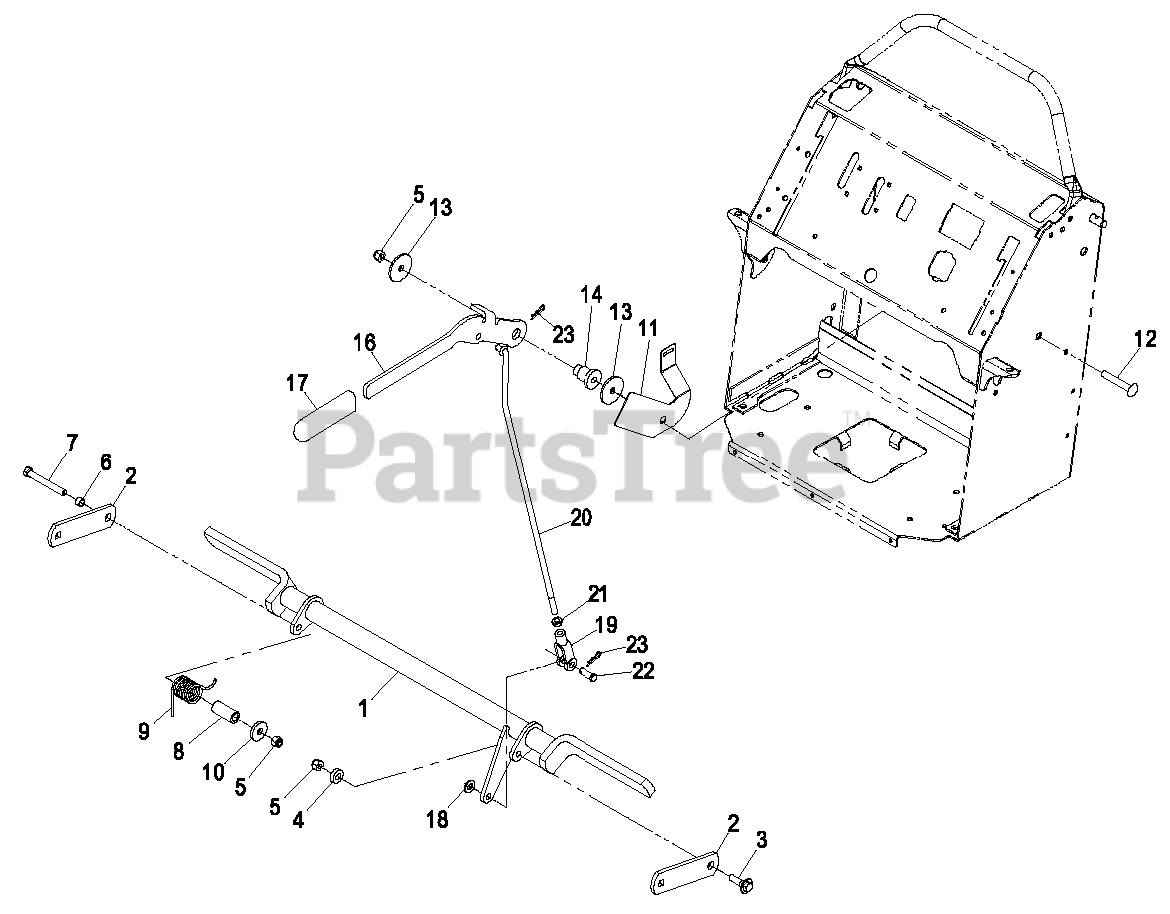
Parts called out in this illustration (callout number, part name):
1	BRAKE ASM
2	SUPPORT-BRAKE
3	SCREW-SHOULDER, HWH
4	SPACER
5	NUT-LOCK, NI
7	SCREW-CARR
9	SPRING-TORSION
11	PLATE-SWITCH, BRAKE
12	SCREW-CARR
13	WASHER-REBOUND
14	MOUNT-PULLEY
16	LEVER-BRAKE
17	GRIP-LEVER
18	WASHER-FLAT
19	YOKE-LINKAGE, BRAKE
20	ROD-BRAKE
21	NUT-HJ
22	PIN-CLEVIS
